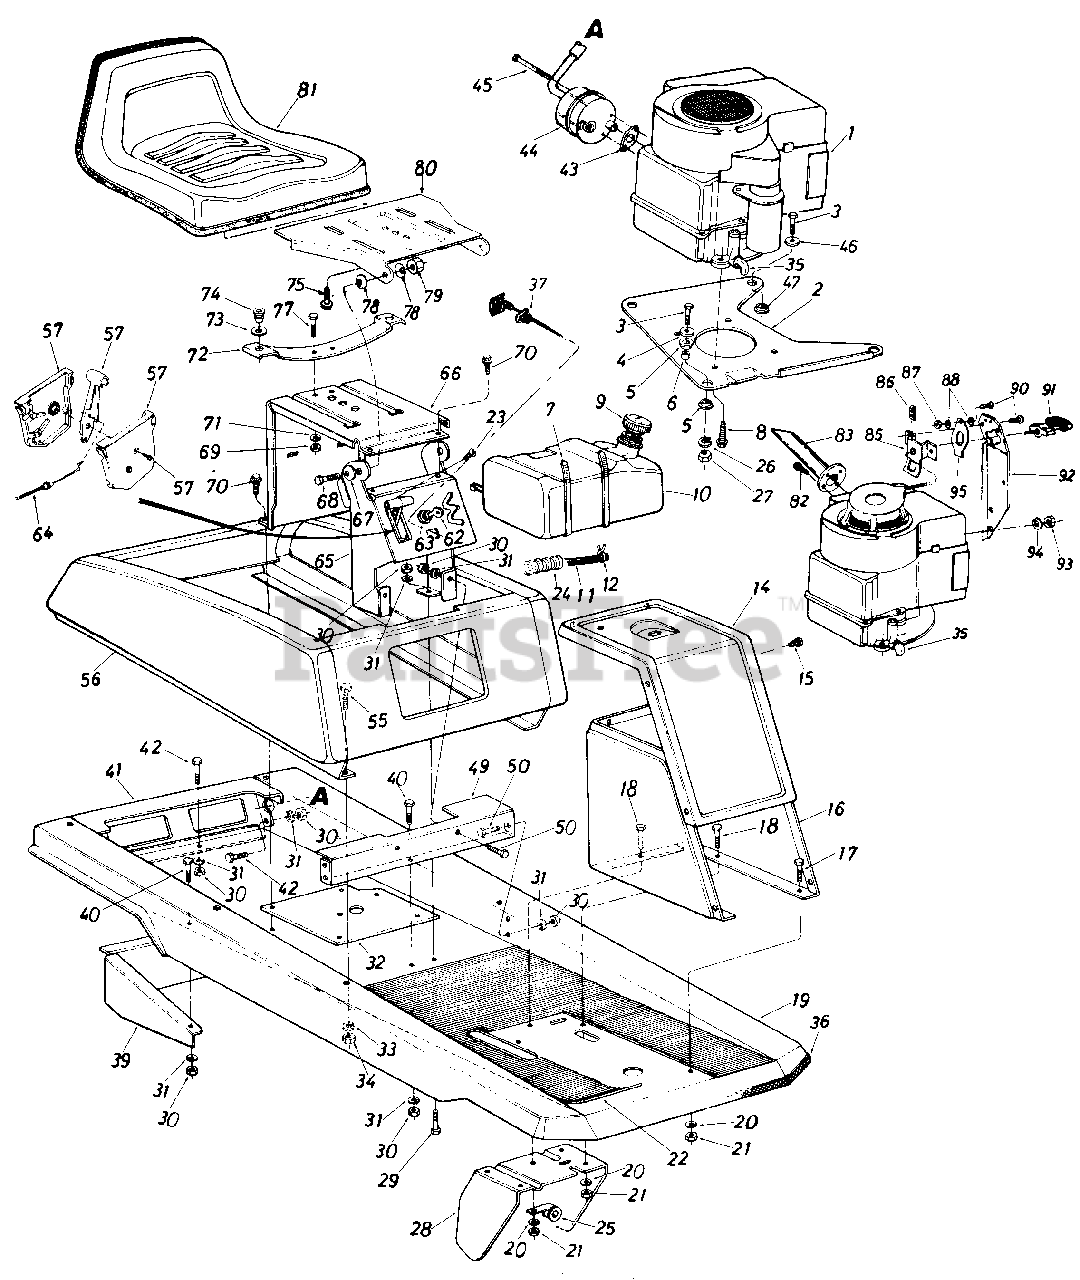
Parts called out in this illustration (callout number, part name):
1	Engine
2	Engine Mounting Plate
3	Hex Bolt 5/16-24 x 1.25" Lg.*
4	Fl-Wash. .330" I.D. x 1.125" O.D.
5	Engine Mounting Grommet
6	Spacer .315" I.D. x .50" O.D. x .520" Lg .
7	Cable Tie 30.6 Lg.
8	Hex Wash. Hd. Self-Tap Scr. 3/8-16 x 1.25" Lg.
9	Gas Gauge
10	Fuel Tank
11	Gas Line
12	Hose Clamp-.406" Dia.
22	Floor Mat
23	Truss Mach. AB-Tap Scr. #10 x .50" Lg.
24	Convoluted Conduit
25	Clamp
26	L-Wash. 5/16" I.D.*
27	Hex Nut 5/16-24 Thd.*
28	Clutch-Brake Pedal Ass'y.
29	Hex Bolt 5/16-18 x .75" Lg*
30	Hex Nut 5/16-18 Thd.*
31	L-Wash. 5/16" I.D.*
32	Mounting Brkt. Variable Speed Pulley
33	L-Wash. 1/4" I.D.*
34	Hex Nut 1/4-20 Thd.*
35	90ø Elbow Male To Female
36	Trim Strip 18" Lg.
37	Choke Control
39	Transaxle Support Ass'y.
40	Hex Bolt 5/16-18 x .75" Lg.*
43	Exhaust Gasket
44	Muffler Ass'y.
45	Shld. Bolt
46	Fl-Wash. .330" I.D. x 1.25" O.D.
47	Flange Wash. .320" I.D. x .750" O.D.
49	Seat Support & Frame Brkt.
50	Hex Bolt 5/16-18 x .75" Lg.
55	Hex Bolt 1/4-20 x .50" Lg.
57	Throttle Control Box Ass'y.
62	Ignition Key
63	Ignition Switch
64	Throttle Control Wire-35"
65	Front Seat Bracket
66	Rear Seat Bracket
67	Bell-Wash. .345" I.D. x .88" O.D.
68	Hex Bolt 5/16-18 x .75" Lg.
69	Hex Nut 5/16-18 Thd.
70	Hex Self-Tap Scr. 5/16-18 x .75" Lg.
71	L-Wash. 1/4" I.D.*
72	Seat Spring
73	Fl-Wash. .531" I.D. x .930" O.D.
74	Grommet
75	Hex Wash. Hd. Tap Scr. 3/8-16 x 3/4" Lg.
77	Hex Bolt 1/4-20 x .75" Lg.
78	Bell-Wash. .345" I.D. x .88" O.D.
79	hex Cent. L-Nut 5/16-18 Thd.
80	Seat Pivot Bracket
81	Seat Ass'y. Comp.
82	Hex Wash. Hd. TT-Tap Scr. 8-32 x .50" Lg.
83	Exhaust Pipe Ass'y.
85	Switch Brkt. Ass'y
86	Speed Nut #10-24 U-Type
87	Hex Nut #10-24 Thd.
88	Fiber Washer
90	Truss Mach. Scr. #10 x .50" Lg.
91	Plastic Handle
92	Rope Handle Bracket
93	Hex Nut 5/16-18 Thd.
94	L-Wash. 5/16" I.D.
95	Switch Spring
